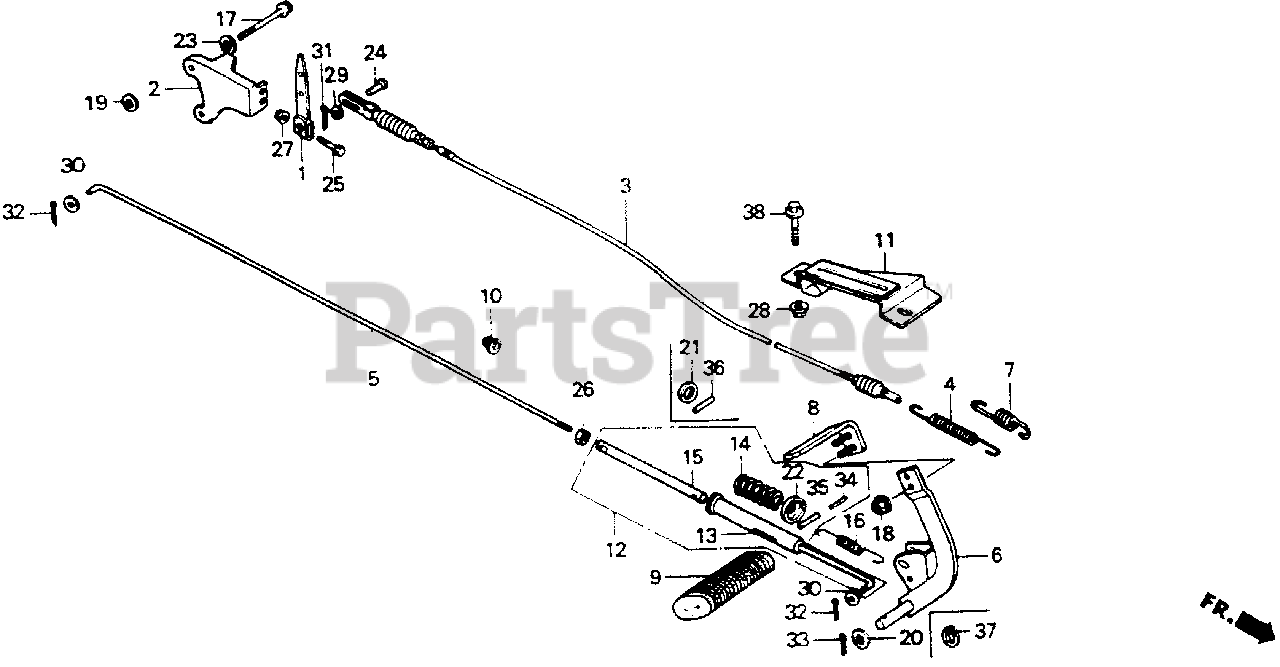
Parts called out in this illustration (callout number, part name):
1	ARM, CLUTCH
2	HOLDER, CLUTCH WIRE
3	CABLE B, CLUTCH (BRAKE) (NOT AVAILABLE)
4	SPRING, CLUTCH
5	ROD A, FOOT BRAKE
6	PEDAL, FOOT BRAKE
7	SPRING, BRAKE PEDAL (NOT AVAILABLE)
8	BRACKET, BRAKE PEDAL
9	RUBBER, BRAKE PEDAL
10	BUSH, BRAKE ROD
12	PIPE ASSY., FOOT BRAKE
13	PIPE, FOOT BRAKE
14	SPRING, BRAKE ROD SETTING
15	SHAFT, SPRING SETTING
16	SPRING, BRAKE DAMPER
17	BOLT, FLANGE (6X65)
18	NUT, FLANGE (8MM)
19	WASHER (6MM)
20	WASHER, THRUST (17MM)
22	WASHER, BRAKE SPRING SETTING
23	WASHER (6X15)
24	PIN, CLUTCH JOINT
25	BOLT, HEX. (5X25)
26	NUT, HEX. (6MM)
27	NUT, FLANGE (5MM)
29	WASHER, PLAIN (6MM)
30	WASHER, PLAIN (5MM)
31	PIN, SPLIT (1.6X12)
32	PIN, SPLIT (2.0X15)
33	PIN, SPLIT (3.0X45)
34	PIN, SPRING (3X28)
35	PIN, SPRING (5X28)
